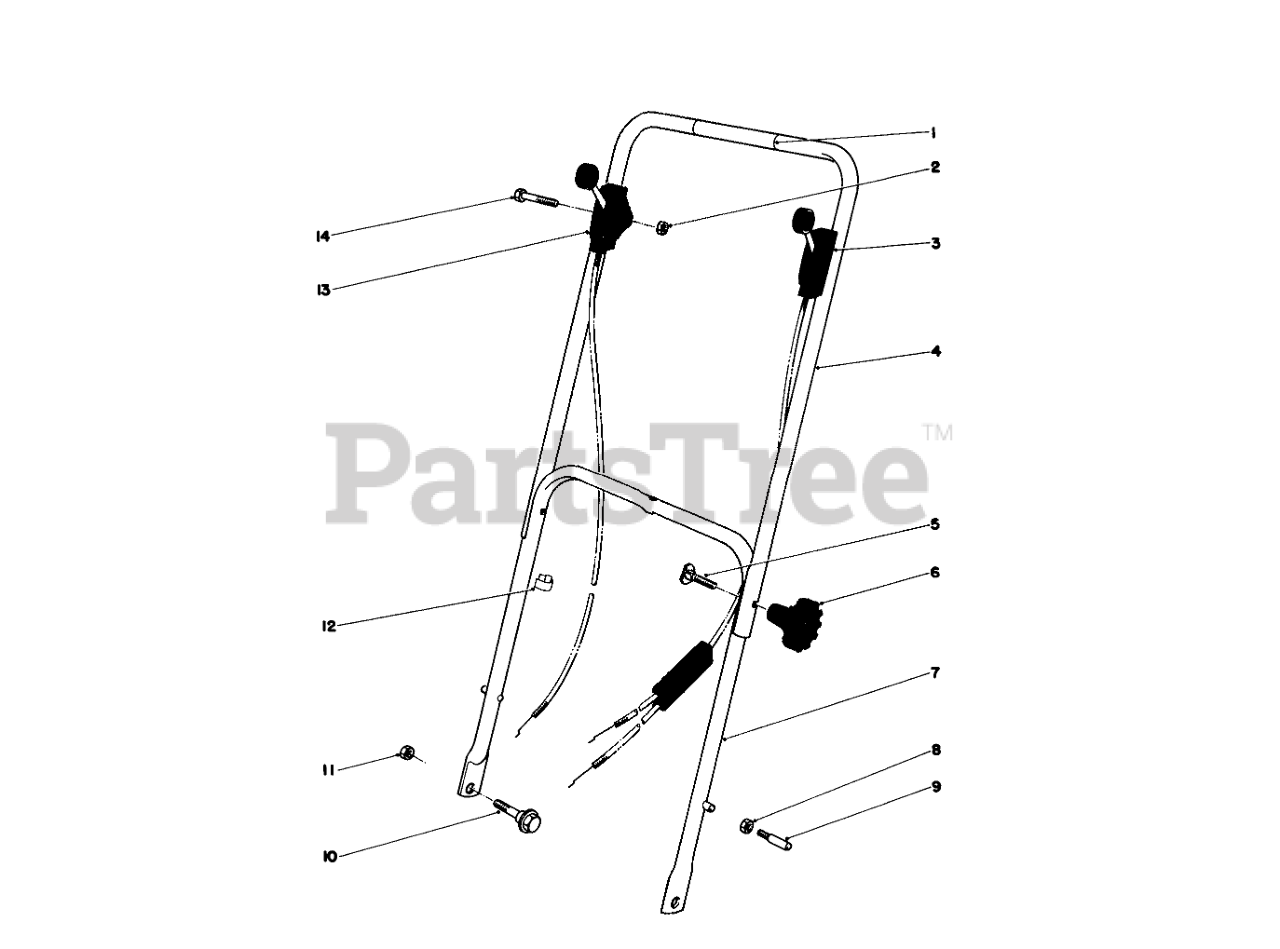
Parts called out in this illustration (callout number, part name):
1	Danger-Decal
2	NUT-LOCK
3	Traction Control
4	Upper Handle
5	HANDLE SCREW
7	LOWER HANDLE ASM SP
8	Nut
9	HANDLE PIN
10	SCREW-SHOULDER
11	Nut
13	Throttle Control
14	SCREW-HH
